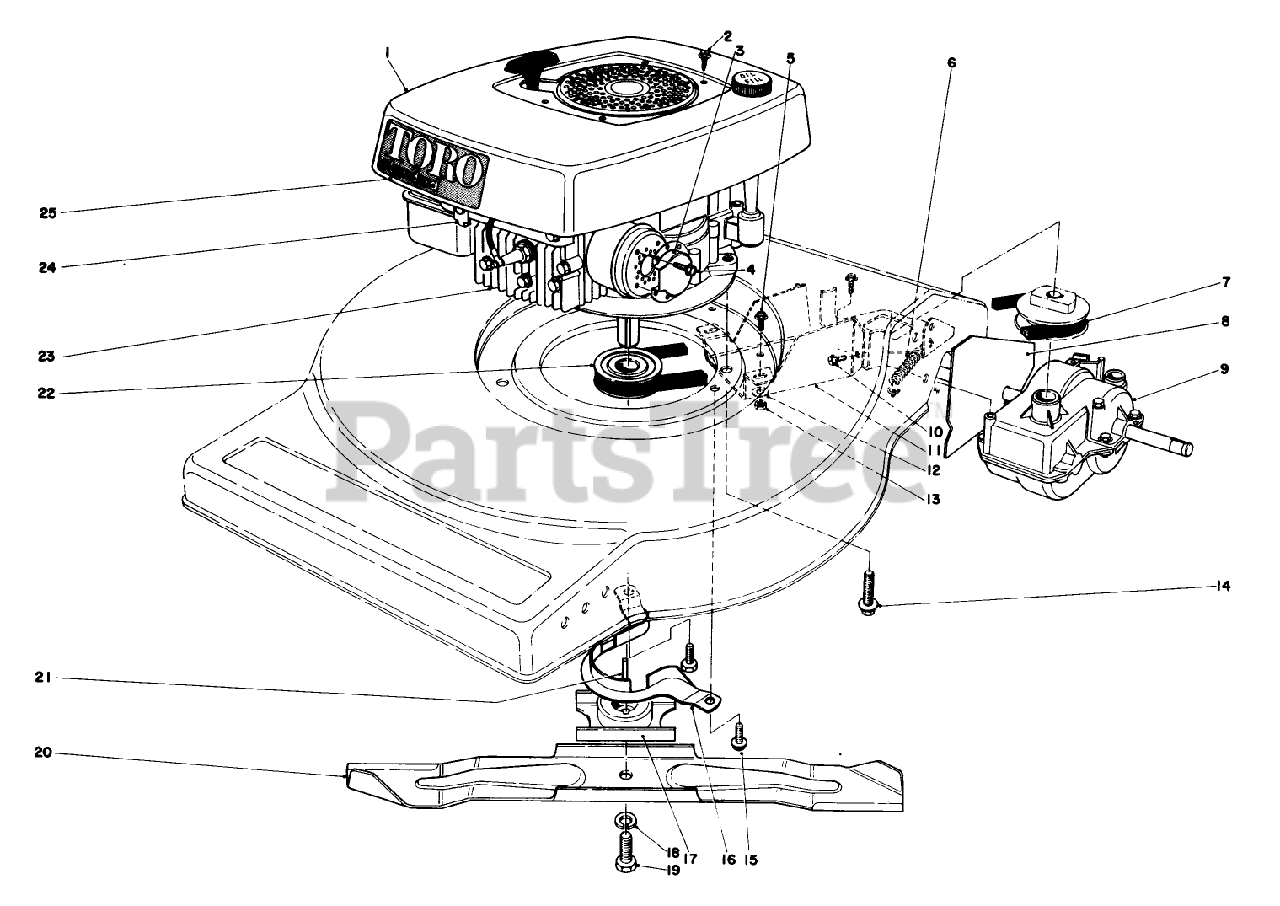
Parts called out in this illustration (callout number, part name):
1	SHROUD
2	8X1/2 SELF TAP SCREW
3	Deflector
4	SCREW W/ENGINE
5	SCREW-HWH
6	IDLER SPRING
7	V-BELT
8	GRASS SHIELD
9	Gear Case Assembly Complete
10	SCREW-HWHTF
11	COVER-BELT
12	WASHER-FLAT
13	Nut
14	SCREW-HWHTF
15	Screw
16	BELT GUIDE
17	Blade Retailer
18	WASHER-LOCK
19	SPECIAL SCREW
20	Blade
21	KEY-SQUARE
22	DRIVER PULLEY
23	Engine
24	Bracket Control
25	Decal Shroud
